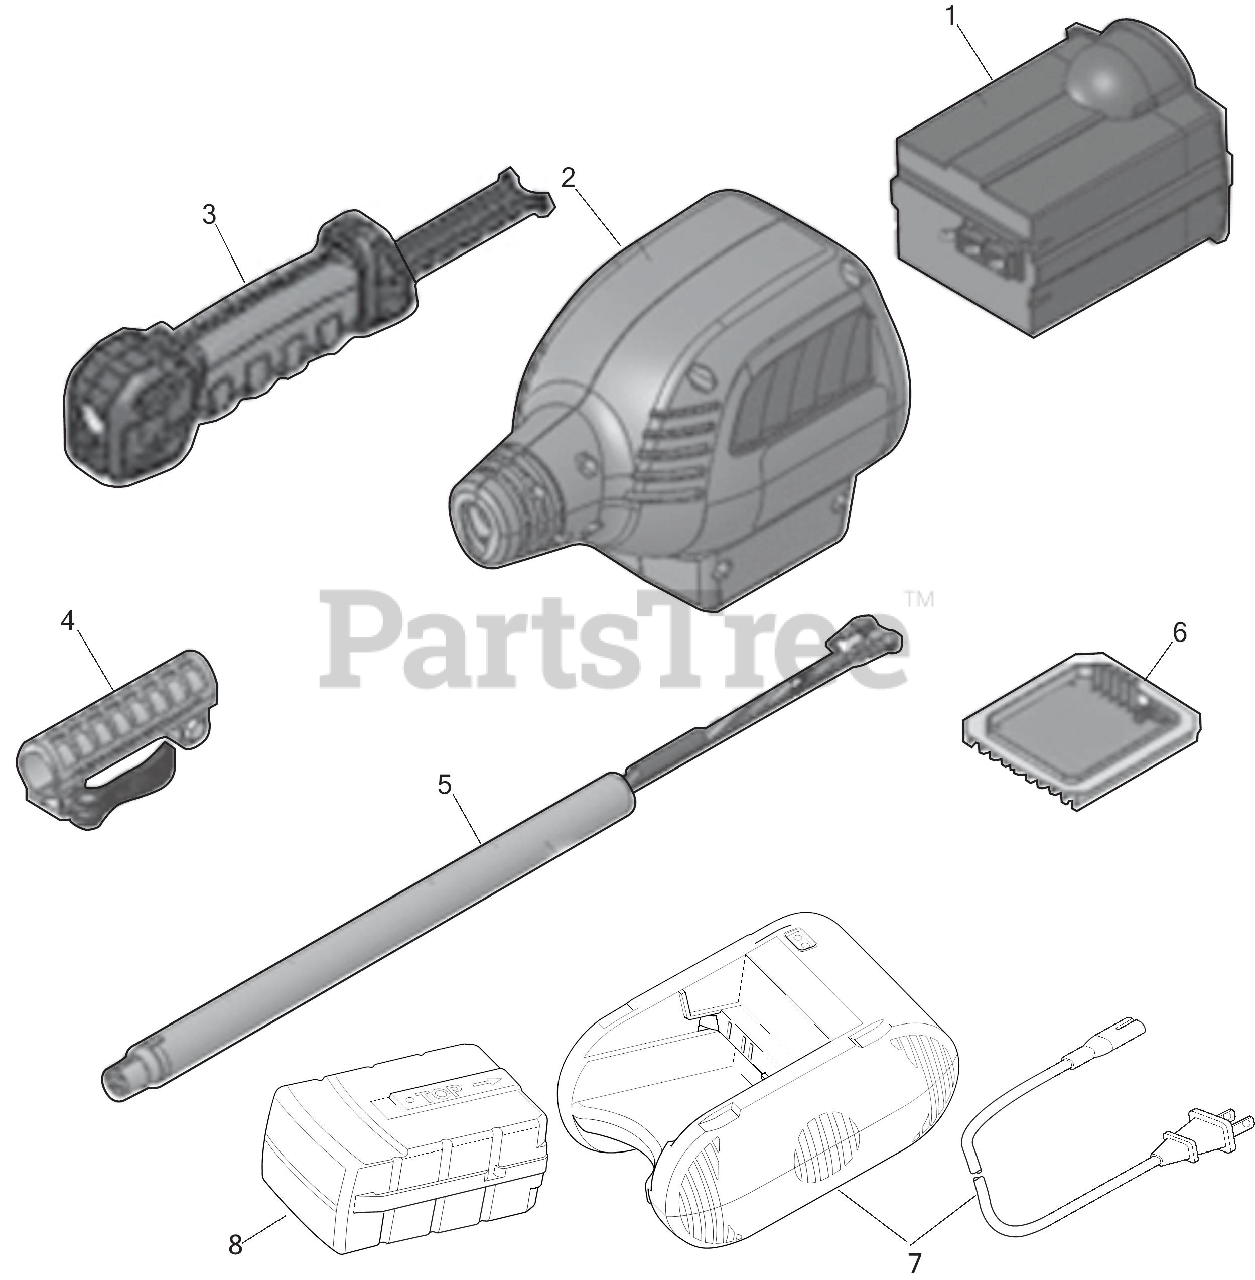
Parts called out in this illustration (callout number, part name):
1	POWER SLEEVE ASSEMBLY
2	POWER HOUSING ASSEMBLY
3	ELITE GRIP ASSEMBLY
4	COUPLER SLV ASSEMBLY CDU400 CORE
5	BOOM ASSEMBLY COMP PRL CDU400
6	CONTROLER CDU400 CORE
7	CHARGER 21V 7AH CRC8000 CORE
8	CORE BATTERY 18.5V
